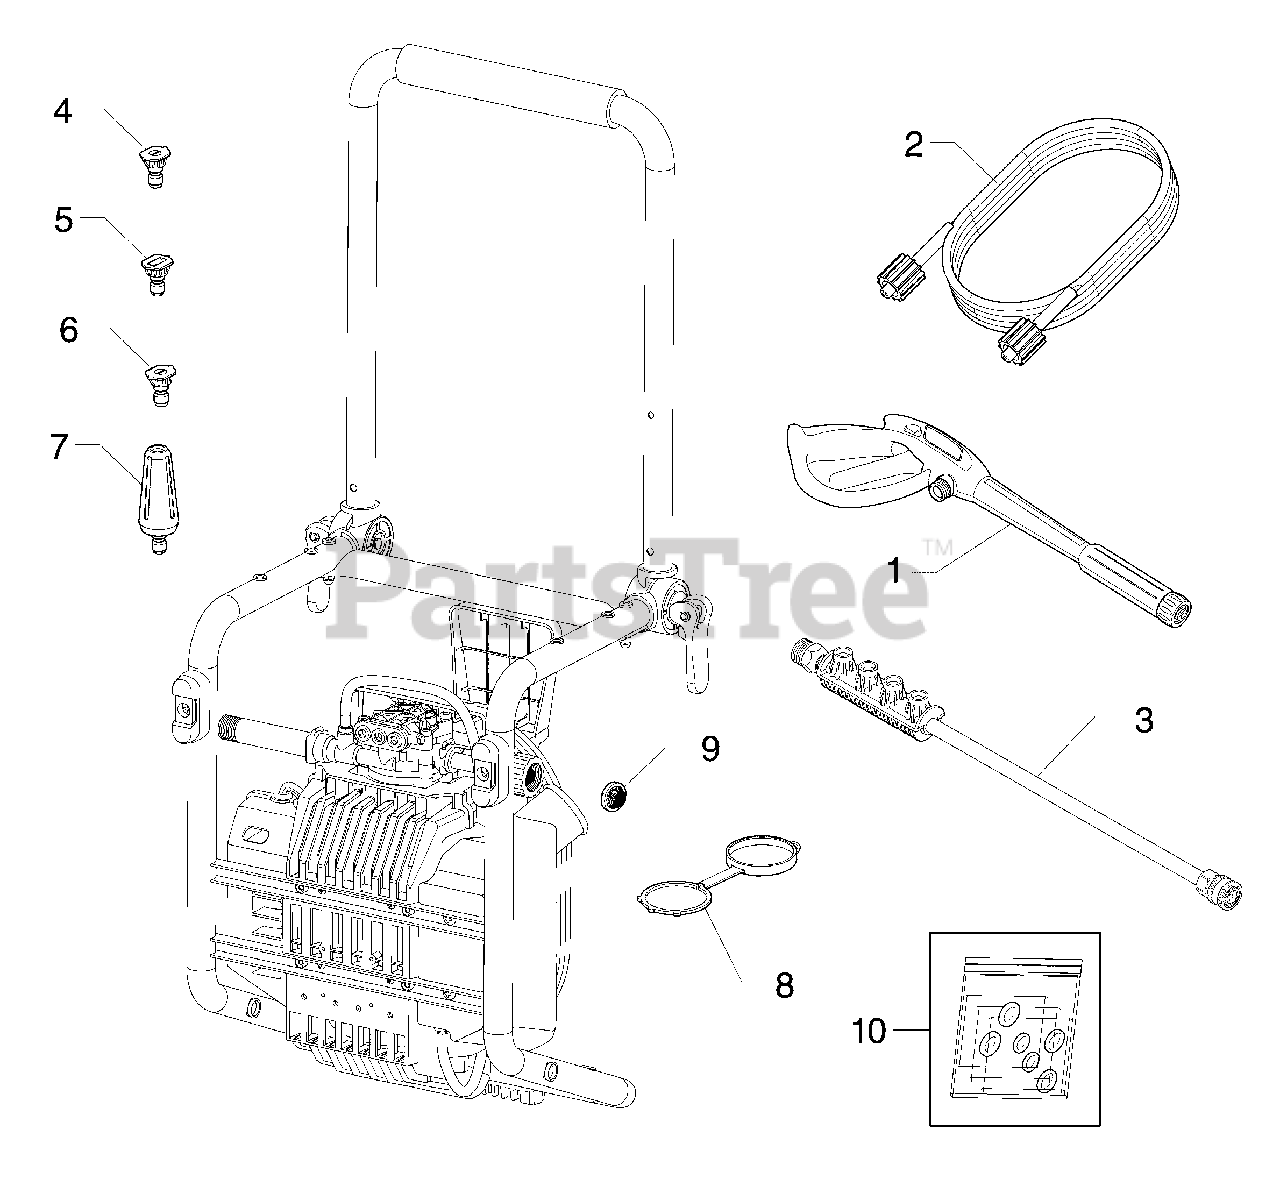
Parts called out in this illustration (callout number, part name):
1	GUN
4	QUICK CONNECT-15
5	QUICK CONNECT-SOAP
6	QUICK CONNECT-25
9	FILTER-GARDEN HOSE
